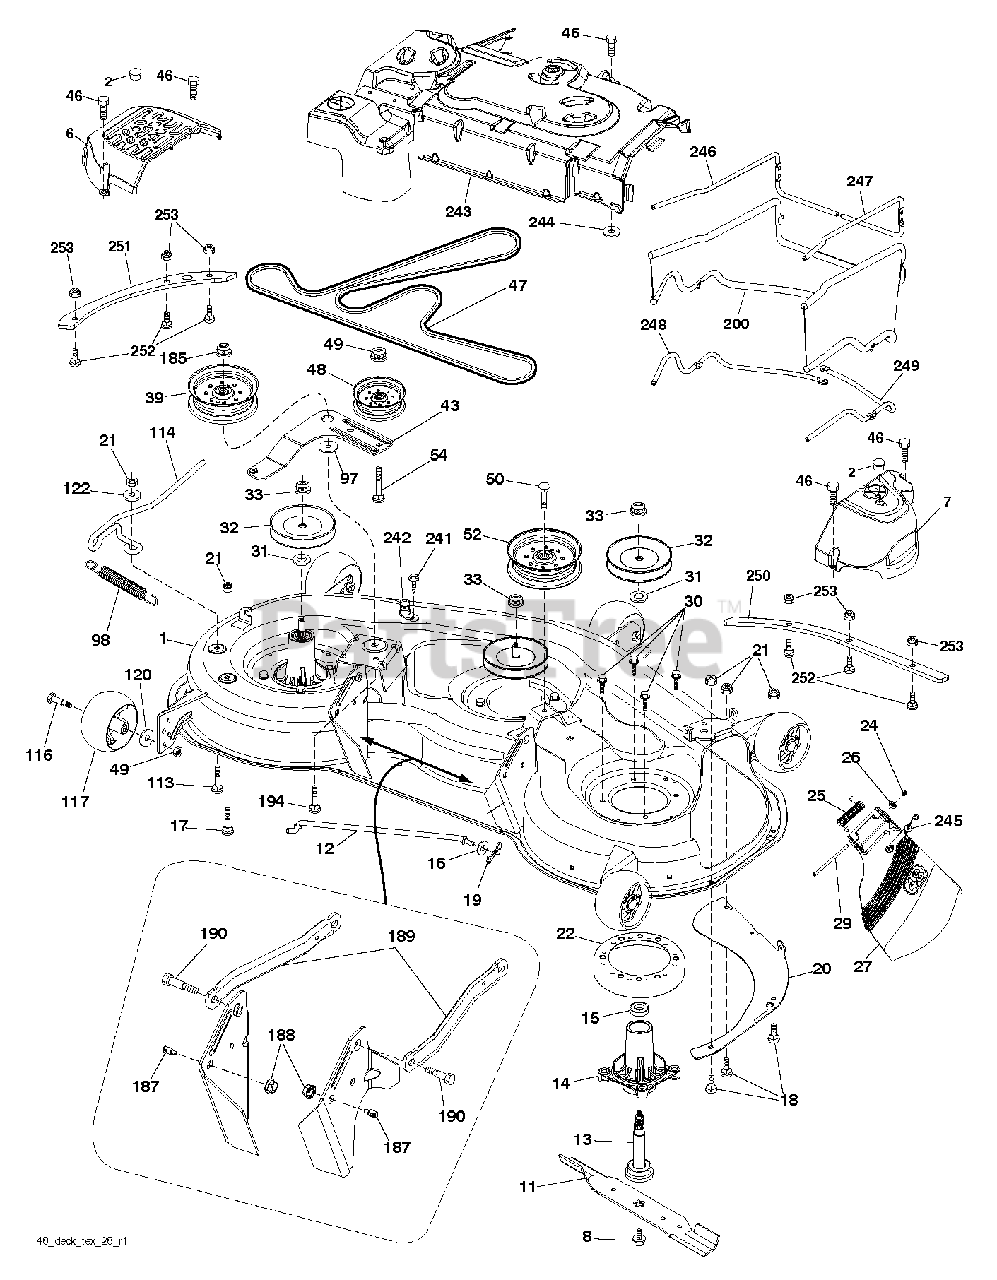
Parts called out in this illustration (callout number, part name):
8	BOLT.WASHER.ASM.7/16-2
11	48" HI-LIFT BLADE
12	ROD.ANTI.SWAY.48/54"TE
13	SHAFT ASM MANDREL
14	HOUSING.MANDREL.4PT.
16	WASHER
17	BOLT
18	BOLT
19	PIN.COTTER.5/16.BOW TI
20	BAFFLE, VORTEX MWR
21	LOCKNUT
22	STRIPPER.MANDREL.ROUND.BLACK
24	CAP-SLEEVE LT
25	SPRING, TORSION
26	NUT PUSH M
29	ROD.HINGE
30	SCREW, WASHER HEAD
31	WASHER.SPACER.MANDREL
32	PULLEY MANDREL
33	NUT.FLANGE.LOCK.TOP
39	RB PULLEY.IDLER.4.50/HUB SPEC
46	SCREW.1/4-20X5/8
47	BELT.DRIVE.DECK
48	PULLEY.IDLER.48"PRIMARY
49	NUT LOCK FLG 3/8-16 UNC
50	SCREW TT 3/8-16X2-1/4 UNC
52	PULLEY.IDLER.2006
54	BOLT.3/8-16X1.50
98	SPRING, DECK DRIVE
114	ROD.TENSION.RELIEF.TEX (2 2)
116	BOLT.SHOULDER.3/8-16X3-5/8.
117	WHEEL. GUAGE RALLY
120	WASHER
122	BUSHING.RELIEF.TENSION
185	NUT.LOCK.FLANGE.7/16
187	STUD.FASTNER.W/ANTI-ROTATE
188	NUT LOCK HEX FLANGE 5/16-18
189	ARM.SUSPENSION.MOWER
190	BOLT.SHOULDER
194	BOLT.HEX.WASHER.HEAD.7/16-24X
241	SCREW.TT.#10-32X.5.3/8.FLANGE
242	PORT.WASHOUT
244	PALNUT 1/4
245	ELASTIC STRAP KIT
250	PLATE.RNFRCMENT.48.FRONT X431
251	PLATE.RNFRCMENT.48.SIDE X431
252	RHSNB, 1/4-20 X 1, GR5
253	NUT T
